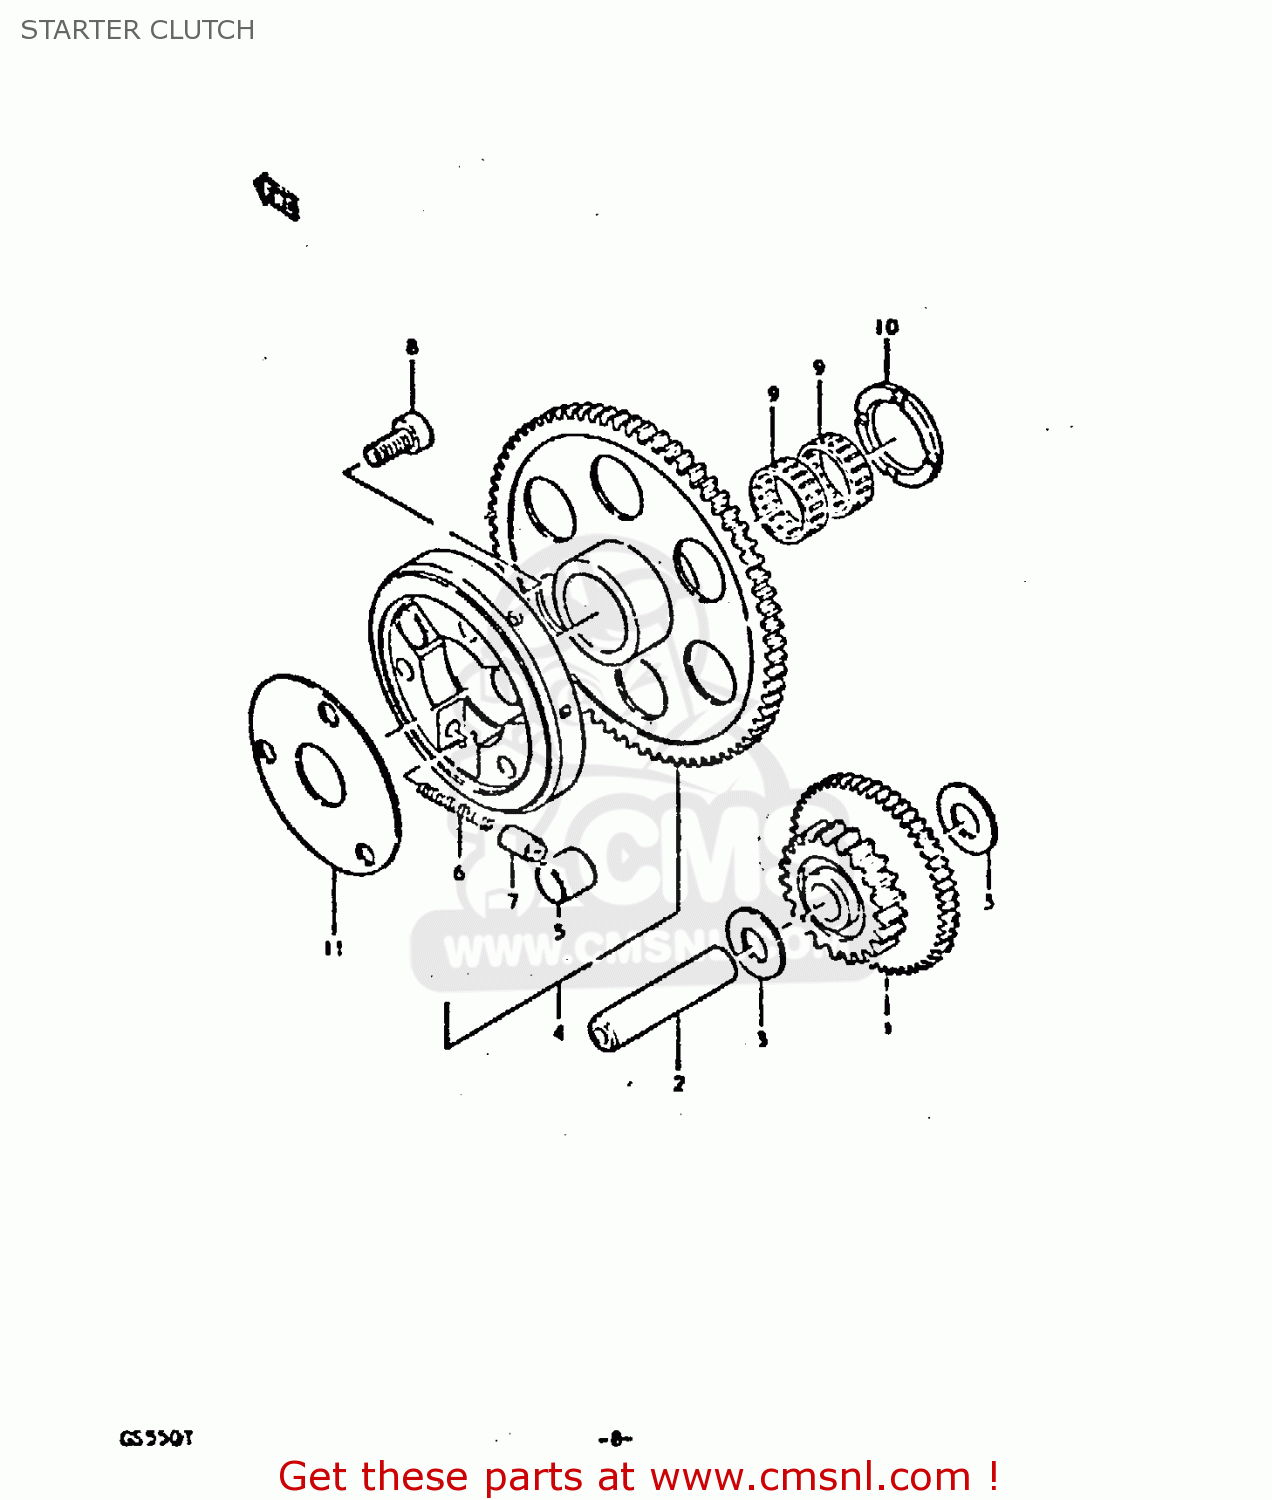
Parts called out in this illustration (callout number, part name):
1	GEAR,STARTER IDLE
2	PIN(7.4X13X56)
3	WASHER(13.3X25X0.85)
4	CLUTCH SET,STARTER
5	ROLLER(15X13)
6	SPRING
7	PIECE,PUSH
8	BOLT
9	BEARING
10	WASHER(25X38X2.5)
11	SHIM,STARTER CLUTCH HUB
